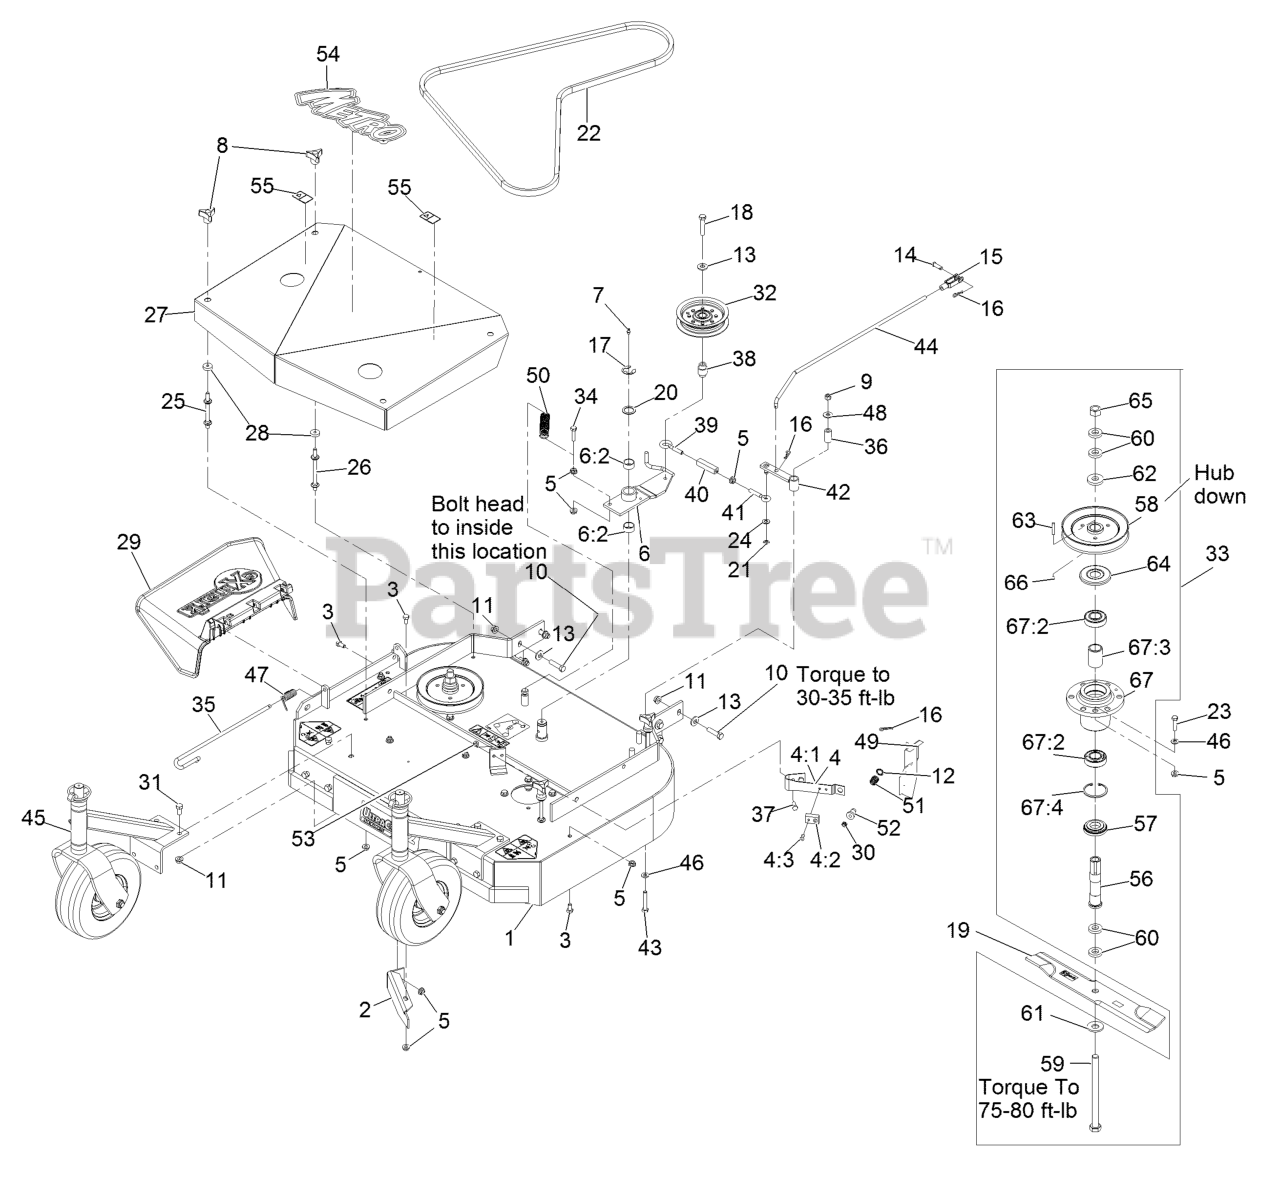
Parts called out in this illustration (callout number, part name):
1	ASM, DECK 32 RIGID
2	BAFFLE-DOGLEG
3	SCREW-HH
4	PAD AND SPRING ASM
4:1	PAD-BRAKE
4:3	RIVET-POP
6	IDLER ARM ASM
6:2	SLEEVE-BEARING
7	FITTING-GREASE
8	KNOB-3 PRONG
9	NUT-LOCK, NI
10	SCREW-HH
11	NUT-HHF, WHIZ
12	RING-PUSH ON
13	WASHER-BELLEVILLE
14	PIN-CLEVIS
15	YOKE-ADJUSTABLE
16	PIN-COTTER
17	RING-RETAINING, EXT
18	SCREW-HH
20	WASHER-SPINDLE
21	RING-RETAINING, EXT
22	BELT,BLADE METRO 32
23	SCREW-HH
24	WASHER-PLAIN
25	STUD-SHIELD, BELT (SHORT)
26	STUD-SHIELD, BELT (LONG)
27	ASM,SHIELD W/DECALS 32 ME
29	CHUTE DEFLECTOR XRK M056
30	NUT-LOCK, NI
31	SCREW-HH
33	ASM, CUTTER HOUSING OUTER
34	SCREW-HH, SPECIAL
35	PIN-CHUTE
36	TUBE-PIVOT
37	SCREW-HH
38	BUSHING-ENGAGEMENT
39	EYEBOLT-THREAD, LH
40	BODY-TURNBUCKLE
41	EYEBOLT-THREAD, RH
42	ARM-ASSIST, 32/36
43	SCREW-HH
44	ARM-ASSIST, LINKAGE
45	ASM,CASTER/MOUNT
46	WASHER-SPRING
47	SPRING, TORSION
48	WASHER-FLAT
49	ROD-BRAKE
50	SPRING-EXTENSION
51	SPRING-COMPRESSION
52	SPACER-FLANGED
53	NUT-LOCK, NI
54	DECAL,METRO MODEL
55	DECAL-WARNING
56	TUBE-SPINDLE, SHORT
57	SPACER-GUARD, BOTTOM
58	SHEAVE
59	SCREW-CAP, HH
61	WASHER-SPRING
62	WASHER-RETAINER, SHEAVE
64	GUARD-BEARING, TOP
65	NUT-HEX
66	SETSCREW
67	KIT, CUTTER HOUSING
67	Cutter Housing ASM
67:2	BEARING-JACKSHAFT
67:3	SPACER-BEARING
67:4	RING-SNAP
